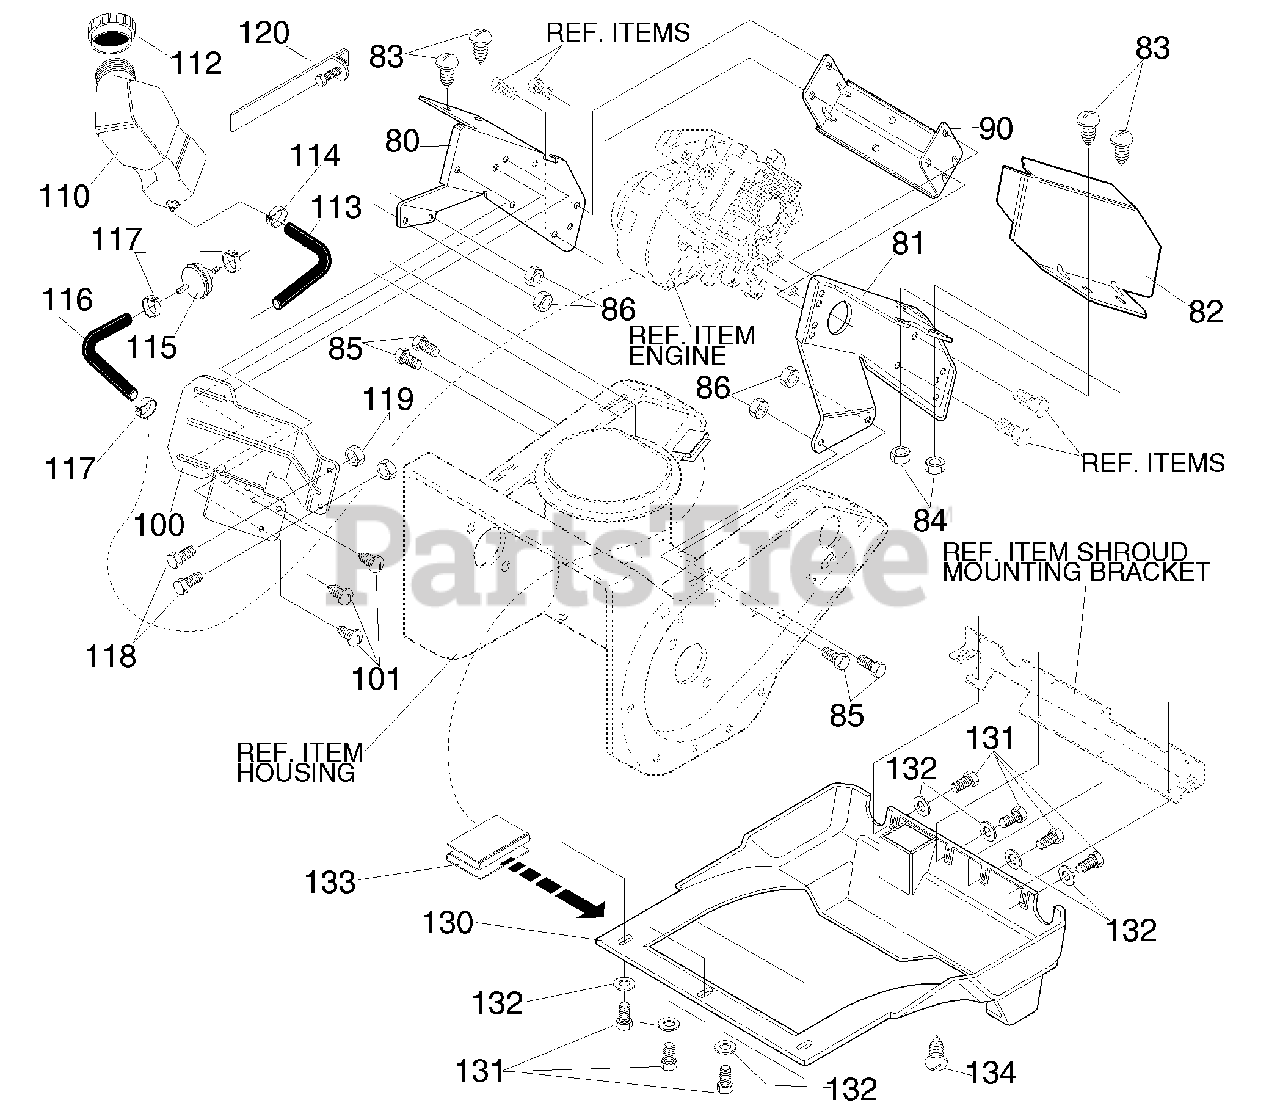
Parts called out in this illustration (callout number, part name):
80	PLATE, REAR MT. RH
81	PLATE, REAR MT. LH
82	SHIELD, ENGINE HEAT
83	SCREW, 1/4-20 X .63
84	NUT, 1/4-20 WDFL
85	SCREW, 5/16-18 X .50 HHC
86	NUT, 5/16-18 REGHEXCTRLK
90	SUPPORT, FRAME ENG. MNT
100	BRACKET, GAS TANK 2CY
101	SCREW, #10-24 X .63
110	TANK, FUEL, 1.62 QT.
112	CAP,FUEL, W/2654 SEAL
113	TUBING, GAS LINE 8 IN.
114	CLAMP,HOSE SCREW TYPE
115	FILTER, IN-LINE
116	TUBING, GAS LINE 3 IN.
117	CLAMP, HOSE
118	SCREW, 10-24 X .50
119	NUT, #10-24 REGHEXCTRLK
120	CLAMP, WORM DR
130	SHROUD, BOTTOM
131	SCREW, #10-24 X .63
132	FLATWASHER .203 X .56 X .040
133	CLIP, "S" TINNERMAN
134	SCREW, 10-16 X .50
